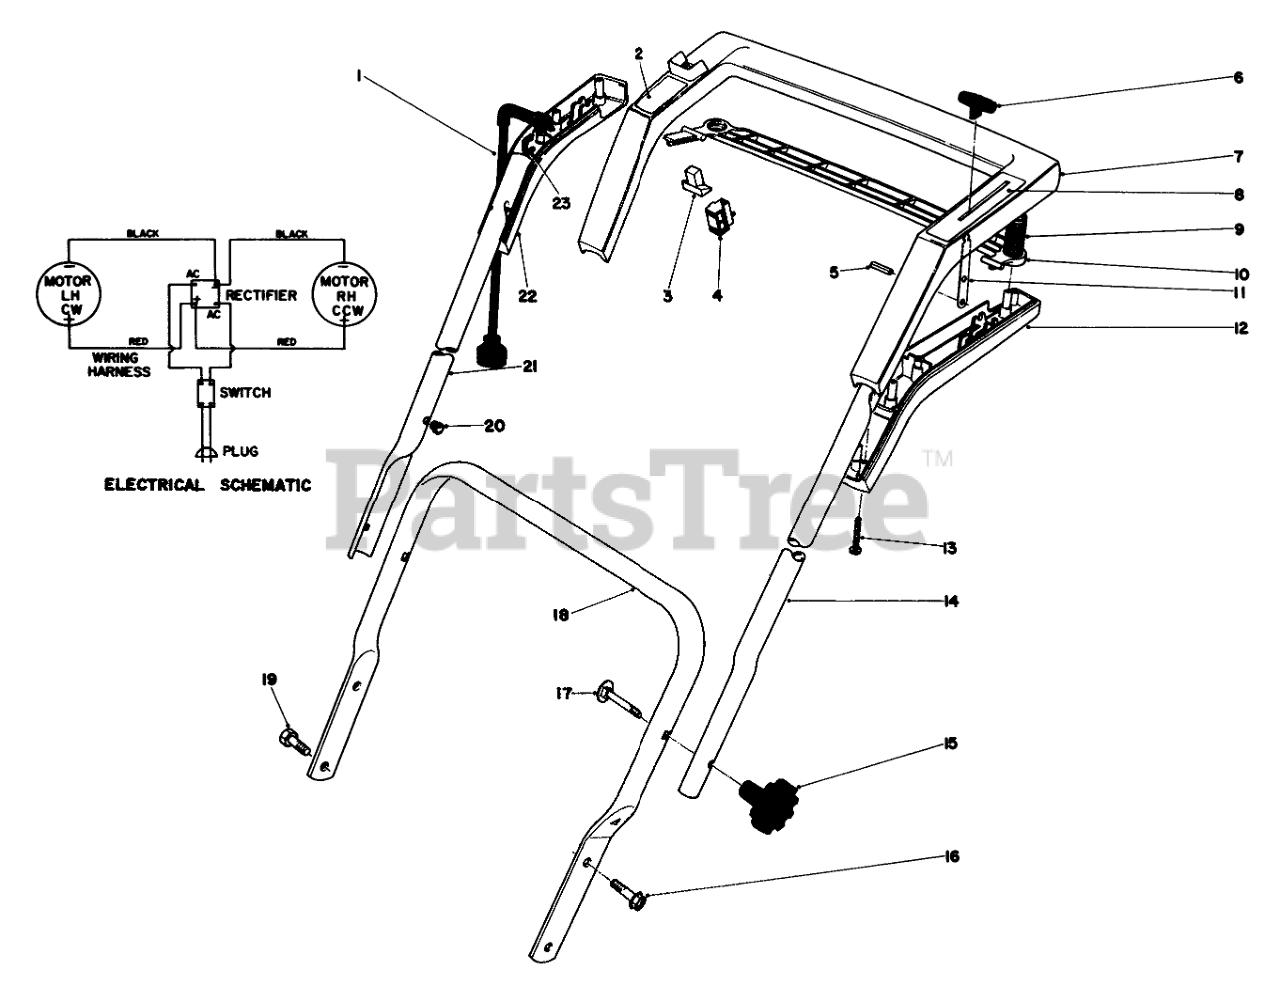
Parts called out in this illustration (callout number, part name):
1	Plug-Pig Tail
2	Decal-On/Off
3	SWITCH BUTTON
4	Switch-On/Off
5	PIN-SPRING
6	CONTROL KNOB
7	Handle Grip
9	COMP SPRING
10	Squeeze Lever
11	Control Lever
12	LH HANDLE GRIP COVER
13	SCREW-PPH
14	Handle-Lower
16	He Ha. Screw
17	SCREW-HANDLE
18	Handle-Lower,
19	SCREW-HH
20	Bushing
21	Handle-Upper R.H.
22	Cover-Handle Grip R.H.
23	Clamp-Wire
